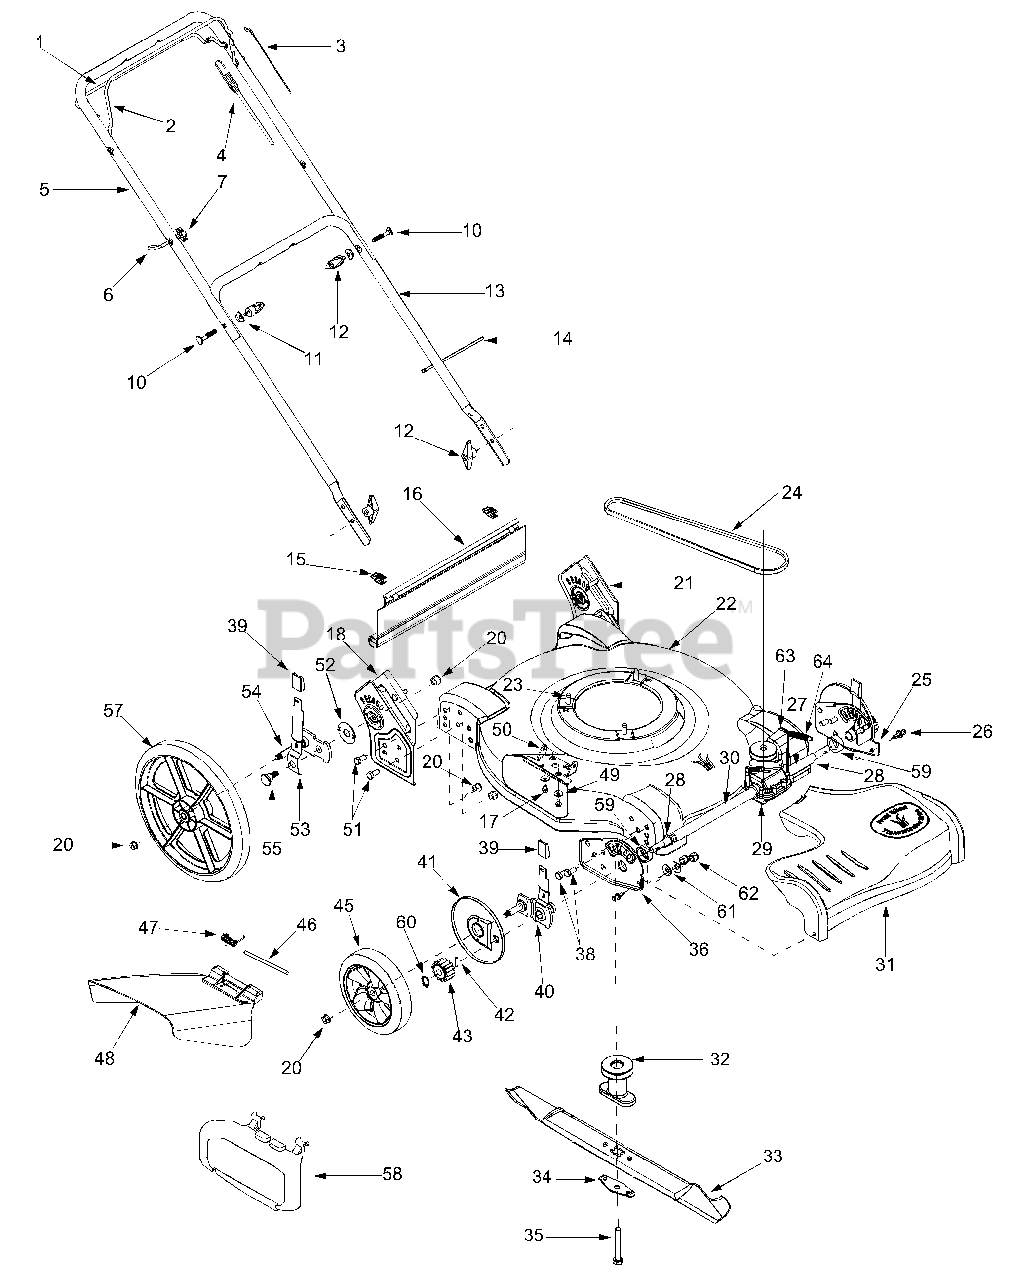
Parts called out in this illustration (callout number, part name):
1	Drive Control Handle
3	Blade Control Cable - 37.75"
3	Blade Control Cable - 40.75"
3	Blade Control Cable- 50.5"
4	Drive Control Cable
6	Eye Bolt
7	Wing Nut 1/4-20
10	Carriage Bolt 5/16-18 x 2.0
11	Shoulder Washer.320 ID x.93 OD
12	Wing Nut
14	Cable Tie
15	Hinge Clip
16	Trail Shield
17	Hex Screw 1/4-20 x.500
20	Lock Nut 3/8-16
23	Hex Washer Screw 3/8-16 x 1.0
24	V-Belt
26	Rivet
27	Sleeve Spacer.550 ID x 3.3
28	Retainer Ring
29	Transmission Assembly Complete
30	Sleeve Spacer.550 ID x 7.95
31	Transmission Cover
32	Blade Adapter
33	22" Mulching Blade
34	Bell Blade Support
35	Hex Cap Screw 3/8-24 x 1.5
38	Hex Cap Screw 3/8-16 x 1.00
39	Adjustment Knob
40	Spring Lever Assembly - RH* (FWD)
40	Spring Lever Assembly - LH* (FWD)
41	Wheel Dust Cover
42	Pin
43	Spur Gear 14T - RH
43	Spur Gear 14T - LH
45	Front Wheel 8 x 1.8
46	Hinge Pin
47	Torsion Spring
48	Side Discharge Assembly
49	Bell Washer.265 ID x.75 OD
50	Deflector Chute Adapter
51	Hex Cap Screw 3/8-16 x.75
52	Thrust Bearing.688 ID x 1.938 OD
53	Spring Lever
54	Rear Pivot Arm Assembly - RH
54	Rear Pivot Arm Assembly - LH
55	Shoulder Screw 3/8-16
57	Rear Wheel 12 x 1.8
58	Snap Mulching Plug
59	Bearing Support Spacer
60	Snap Ring.500
61	Bell Washer.375 x.870 x.063
62	Hex Lock Nut 3/8-16
64	Extension Spring.47 OD x 2.50
